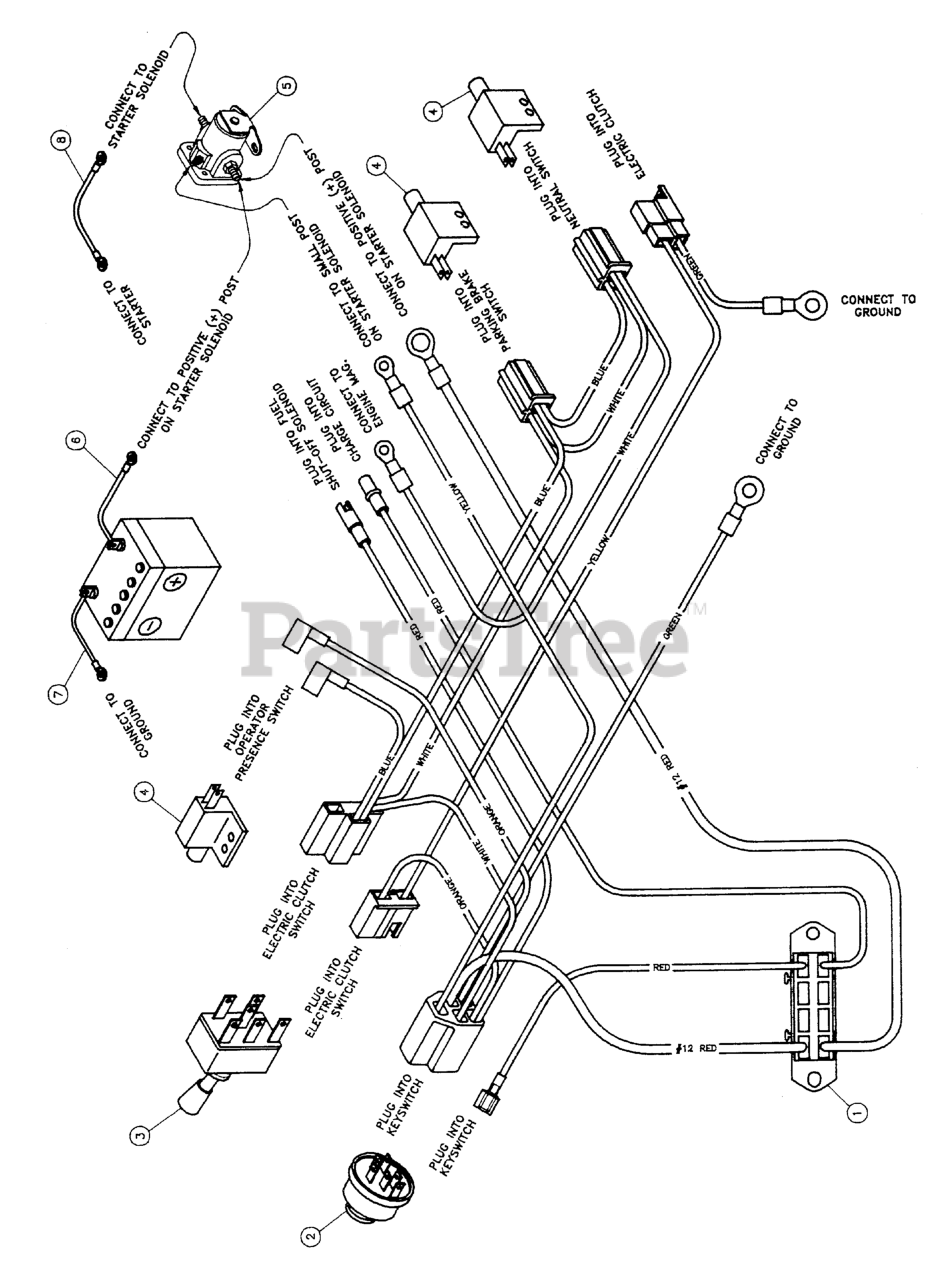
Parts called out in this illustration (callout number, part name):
1	DDSBVE WIRING HARNESS
2	SWITCH, IGNITION, 6 POST
3	SWITCH, Electric Clutch
4	SWITCH, PLUNGER, N.C.
5	SOLENOID, Starter
6	POSITIVE (+) BATTERY CABLE, 30"
7	BATTERY CABLE, NEG, 22, 1/4-5/16
8	Starter Cable
